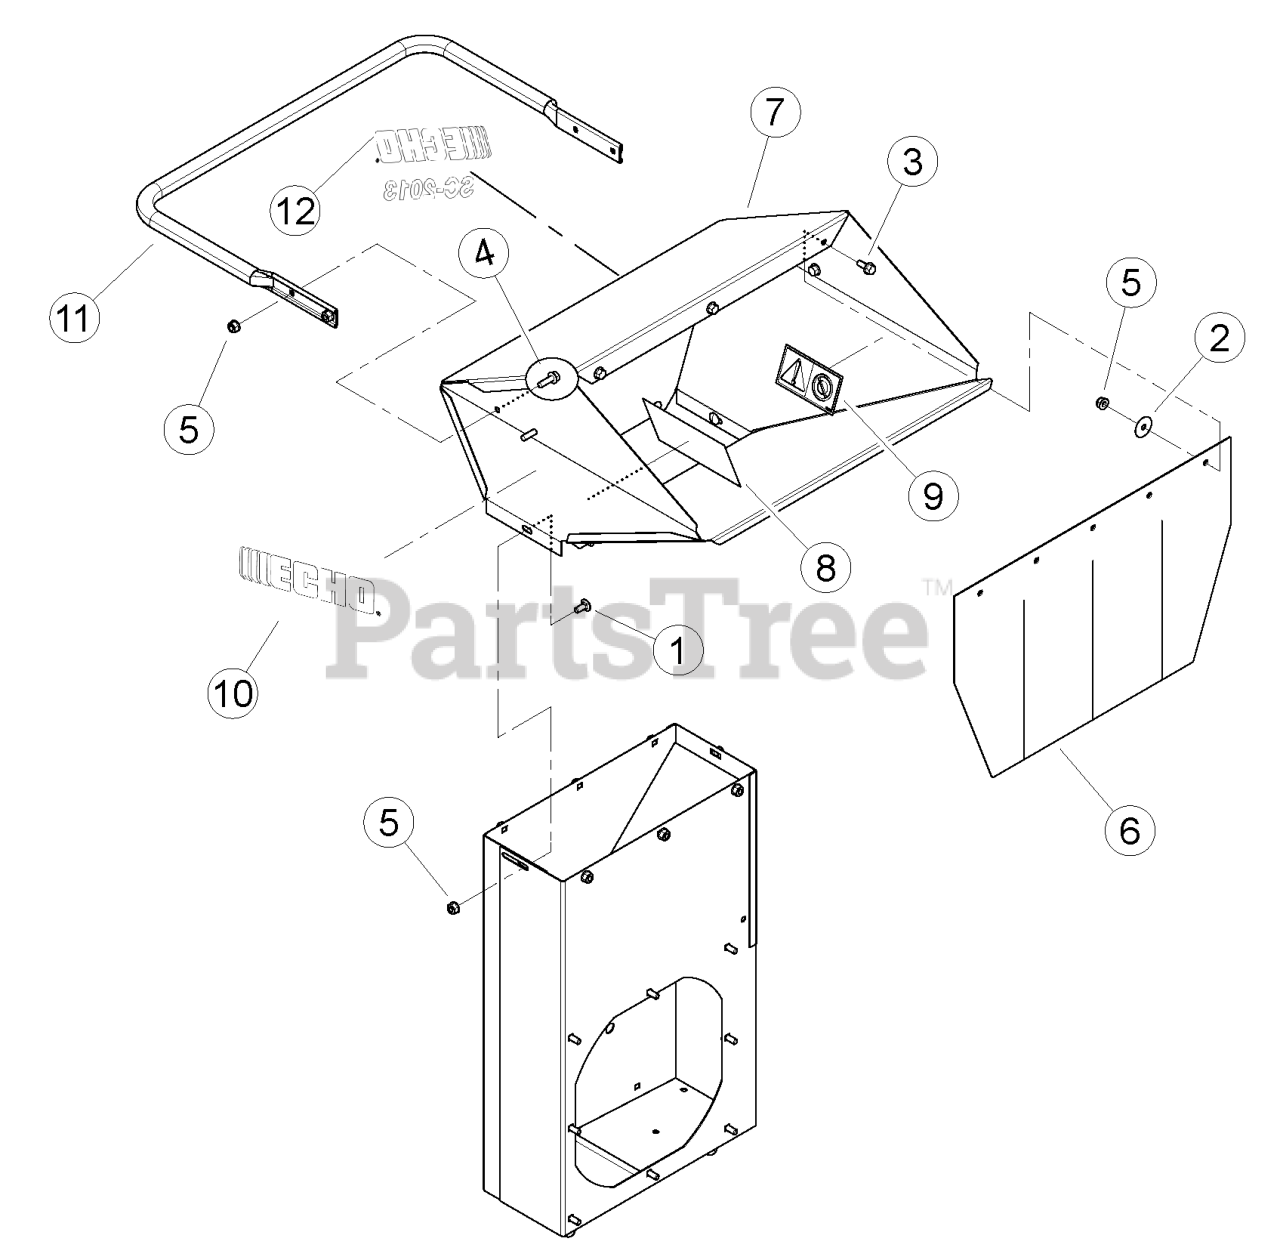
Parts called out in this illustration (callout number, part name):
1	BOLT, 5/16-18 × 3/4 SN GR5 CRG
2	WASHER, 5/16" FENDER ZP
3	BOLT, 5/16 × 3/4 FLANGE NC
4	BOLT, 5/16 × 1 FLANGE NC
5	NUT, 5/16-18 NYLOCK FLANGE
6	BELTING, RENTAL HOPPER
7	ASSEMBLY, NARROW RENTAL HOPPER W/ DECALS
8	DECAL, BLADE DANGER ISO
9	DECAL, SHREDDER SIZE ISO
10	DECAL, ECHO
11	HANDLE, RENTAL HOPPER
12	DECAL, MODEL ECHO SC-2013
